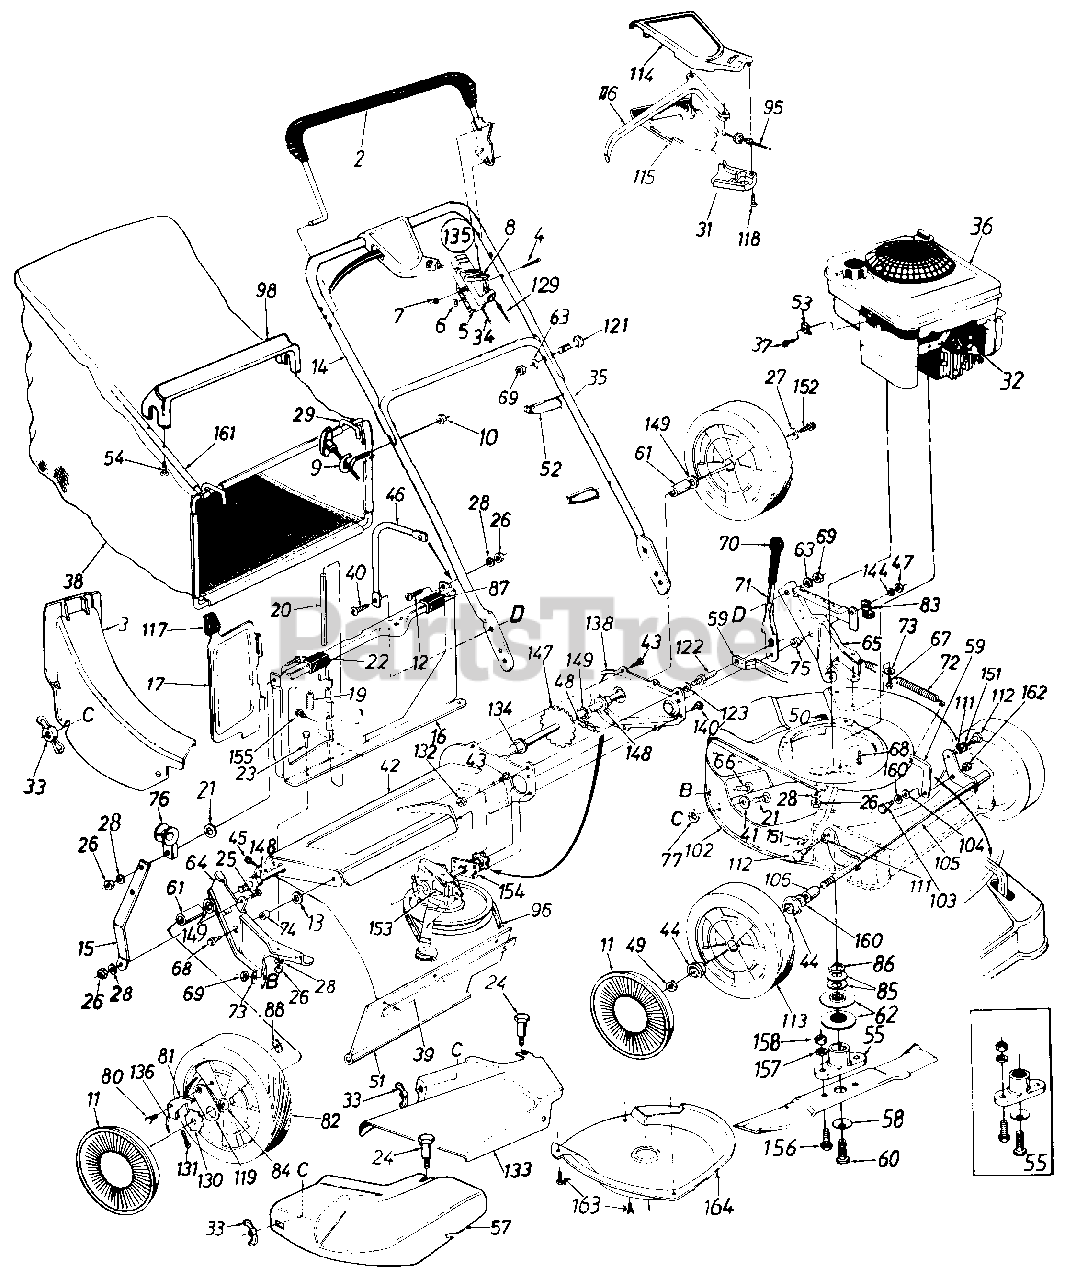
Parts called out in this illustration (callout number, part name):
2	Control Handle Ass'y. - L.H.
3	Rear Discharge Chute Ass'y.
4	Oval C-Sunk Scr.
5	Throttle Body
6	Spr. Wash. .66" I.D.
7	Hex L-Nut 1/4-20 Thd.
8	Throttle Lever
9	Rope Guide Bolt
10	Hex L-Nut 1/4-20 Thd.
11	Hub Cap
12	Truss Mach. Scr. 1/4-20 x .62" Lg.
13	Fl-Wash. .383" I.D. x 1" O.D.
19	Torsion Spring
20	Pivot Pin
21	Carriage Bolt 1/4-20 x .62"
22	Truss Mach. Scr. 1/4-20 x 3/4" Lg.
23	Hex Bolt 1/4-20 x .50" Lg.
24	Shoulder Bolt .312 Dia. x .18 Lg. - Special
25	Hex Bolt 1/4-20 x .62" Lg.
26	Hex Nut 1/4-20 Thd.
27	Bell-Wash. 1/4" I.D.
28	L-Wash. 1/4" I.D.
31	S.P. Control Cover
32	Spark Plug Insulator
33	Wing Nut w/Washer
34	Throttle Control Wire 61"
35	Lower Handle-Painted
36	Engine
37	Hex Self-Tap Scr. #10-32 x .62" Lg.
38	Grass Bag
39	Retaining Strip
40	Truss Mach. Scr. 5/16-18 x .75" Lg.
41	Fl-Wash. .344" I.D. x .62"
44	Flange Ball Bearing 1/2" I.D.
45	Hex AB-Tap Scr. 1/4 x .62"
46	Catcher Panel Support Arm
47	Hex Patch L-Nut 3/8-24 Thd.
48	#48 Chain .500" Pitch x 30 Links
49	Hex L-Nut 1/2-20 Thd.
51	Rear Flap 3.75" x 17.30" Lg.
52	Cable Tie
53	Cable Clamp
54	Hex AB Scr. #12 x 1.25" Lg.
55	Blade Adapter Kit
57	Mulching Plate
58	Bell-Wash. .46" I.D.
59	Height Adj. Connecting Arm
60	Hex Bolt 7/16-20 x 1.5" Lg. (Grade 5)
61	Spacer .513" I.D. x .703" O.D. x .69" Lg.
62	Serrated Pulley Half
63	L-Wash. 5/16" I.D.
64	R.H. Handle Wheel Brkt. Ass'y.
65	L.H. Handle Wheel Brkt. Ass'y.
66	Carriage Bolt 5/16-18 x .62"
67	Hex Wash. Hd. B-Tap Scr.
68	Hex Wash. Hd. TT-Tap Scr.
69	Hex Nut 5/16-18 Thd.
70	Grip (Grade 5)
71	Height Adj. Lever
72	Extension Spring .75" O.D. x 8" Lg.
73	Bell-Wash. 5/16" I.D.
74	Spacer
75	Shld. Spacer .500" Dia.
76	Rope Guide
77	Bolt Retainer 1/4 x .50" O.D.
80	Shld. Scr. .342" Dia. x .268
81	Pawl
82	Rear Wheel Ass'y. Comp.
84	Bearing 1/2" I.D.
85	Bell-Washer 1.01" I.D.
86	Crankshaft Spacer
87	Panel Clip
88	Weld L-Nut 1/4-20 Thd.
95	S. P. Cable
96	"V"-Belt
98	Bag Handle
102	21" Deck Ass'y.
103	Shld. Bolt .5" Dia. x .295
104	Bell-Wash. .515" I.D. x 1.0" O.D.
105	Front Axle Ass'y.
106	Sleeve .526" I.D. x.690" O.D. x .880" Lg.
111	Intern. L-Wash. 3/8 I.D.
112	Shld. Bolt .575" Dia. x .42
113	Front Wheel Ass'y. Comp.
114	Self-Propelled Control Cover
115	Self-Propelled Control Cover
116	Control Lever
117	Door Grip
118	Fl-"C"-Sunk Hd. Tap Scr. #10 x .75" Lg.
119	Pawl Plate
121	Curved Carr. Bolt 5/16-18 x 1.38" Lg.
122	Shld. Pin 3/8-24 x 1.43" Lg.
123	L-Wash. 3/8" I.D.
129	Control Cable 47" Lg.
130	Ratchet Wheel 1.62" O.D.
131	Cotter Pin 1/8" Dia. x 1.00" Lg.
132	Hex Jam Nut 3/8-24 Thd.
133	Side Chute Deflector Ass'y.
134	Hex Flange Bearing
136	Spring-nylon
144	Fl-Wash. .385" I.D. x .87"
147	Rear Shaft Ass'y. 21.94" Lg.
148	Hex Flange Bearing .506"
149	Fl-Wash. .531" I.D. x .930"
151	Flanged Nyliner Brg.
152	Hex Bolt 1/4-20 x .62" Lg.
153	Transmission Comp.
155	Hex B-Tap Scr. #10 x .38
156	Hex Scr. 3/8-24 x 1.0" Lg.
157	L-Wash. 3/8" I.D.
158	Hex Nut 3/8-24 Thd.
160	Fl-Wash. .51" I.D. x.75" O.D.
162	Hex Jam Nut 3/8-16 Thd.
163	Hex Wash. Hd. Tap Scr. 1/4 x .5" Lg.
164	Mulching Baffle
